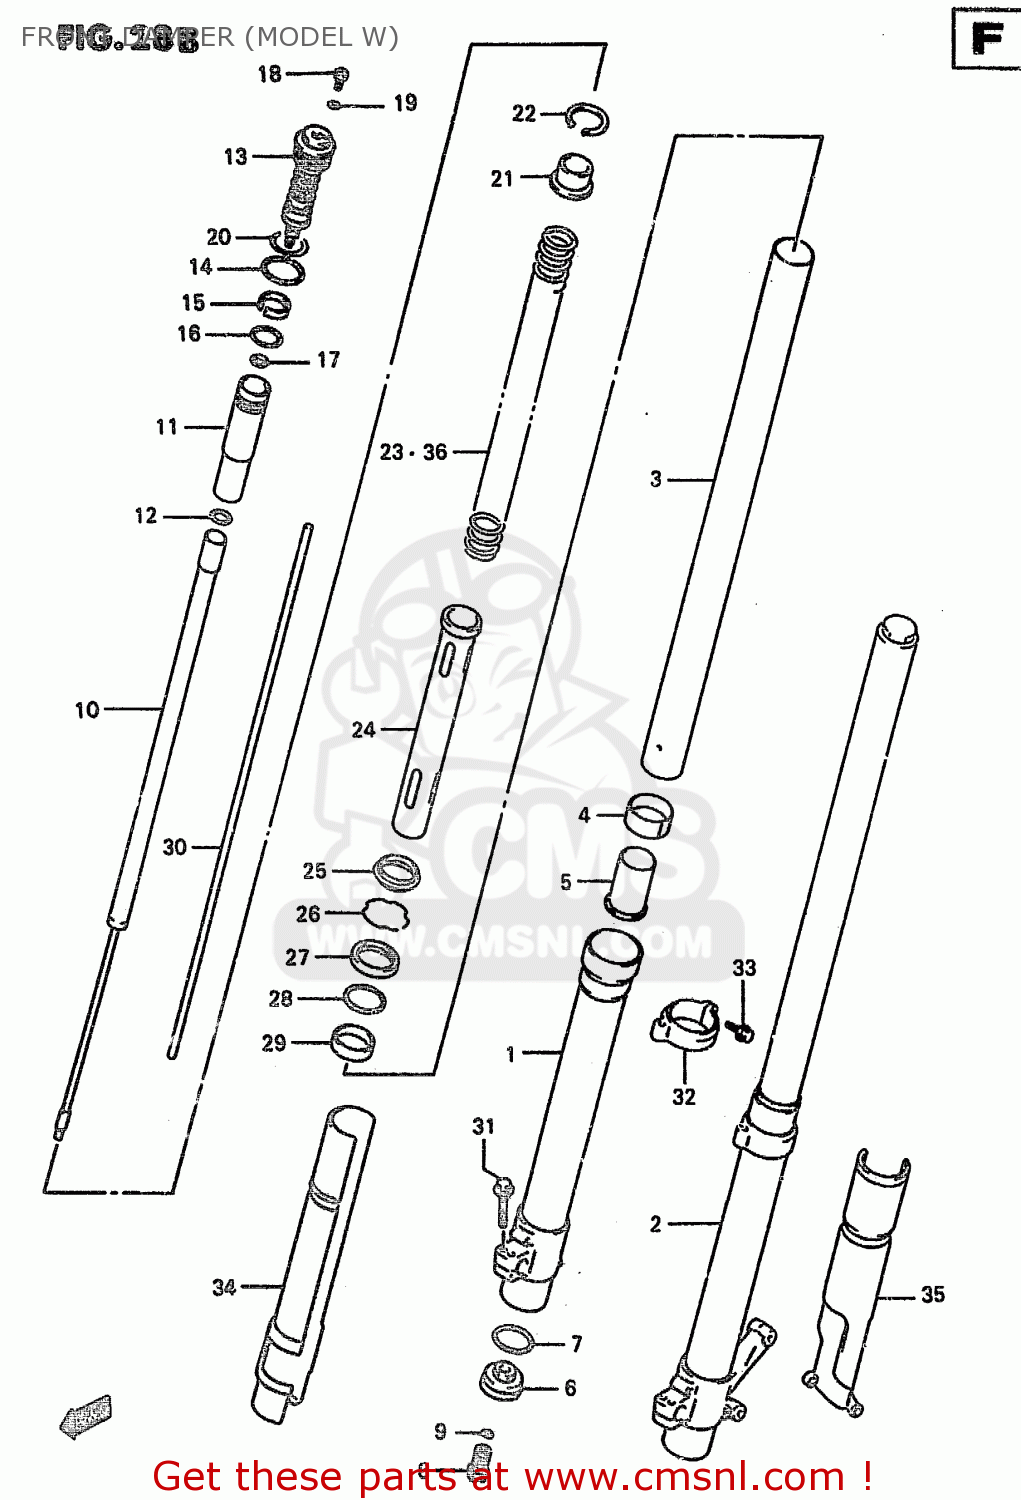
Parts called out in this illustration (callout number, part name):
1	TUBE,OUTER,R
2	TUBE,OUTER,LEFT
3	TUBE,INNER
4	BUSH,SLIDE
5	PIECE,OIL LOCK
6	PLATE,END
7	O RING
8	BOLT,CTR
9	O RING,CTR BOLT
10	ROD,FR DAMPER
11	TANK,SUB
12	O-RING
13	BOLT,FORK
14	O RING
15	BUSHING,SLIDE
16	O RING
17	O RING
18	BOLT,PLUG
19	O RING,PLUG
20	O RING
21	SPRING,STOPPER
22	RING,STOPPER
23	SPRING,FRONT (K=0.42)
24	COLLAR,SPRING
25	SEAL,DUST
26	RING,STOPPER
27	SEAL,OIL
28	SPACER,SEAL
29	BUSH,GUIDE
30	ROD,PUSH
31	BOLT,HANDLE HOLDER(8X35)
32	GUIDE,FR PROTECTOR,R
33	BOLT
34	PROTECTOR,OUTER TUBE,R
35	PROTECTOR,OUTER TUBE,L
36	SPRING,FRONT (K=0.40)
